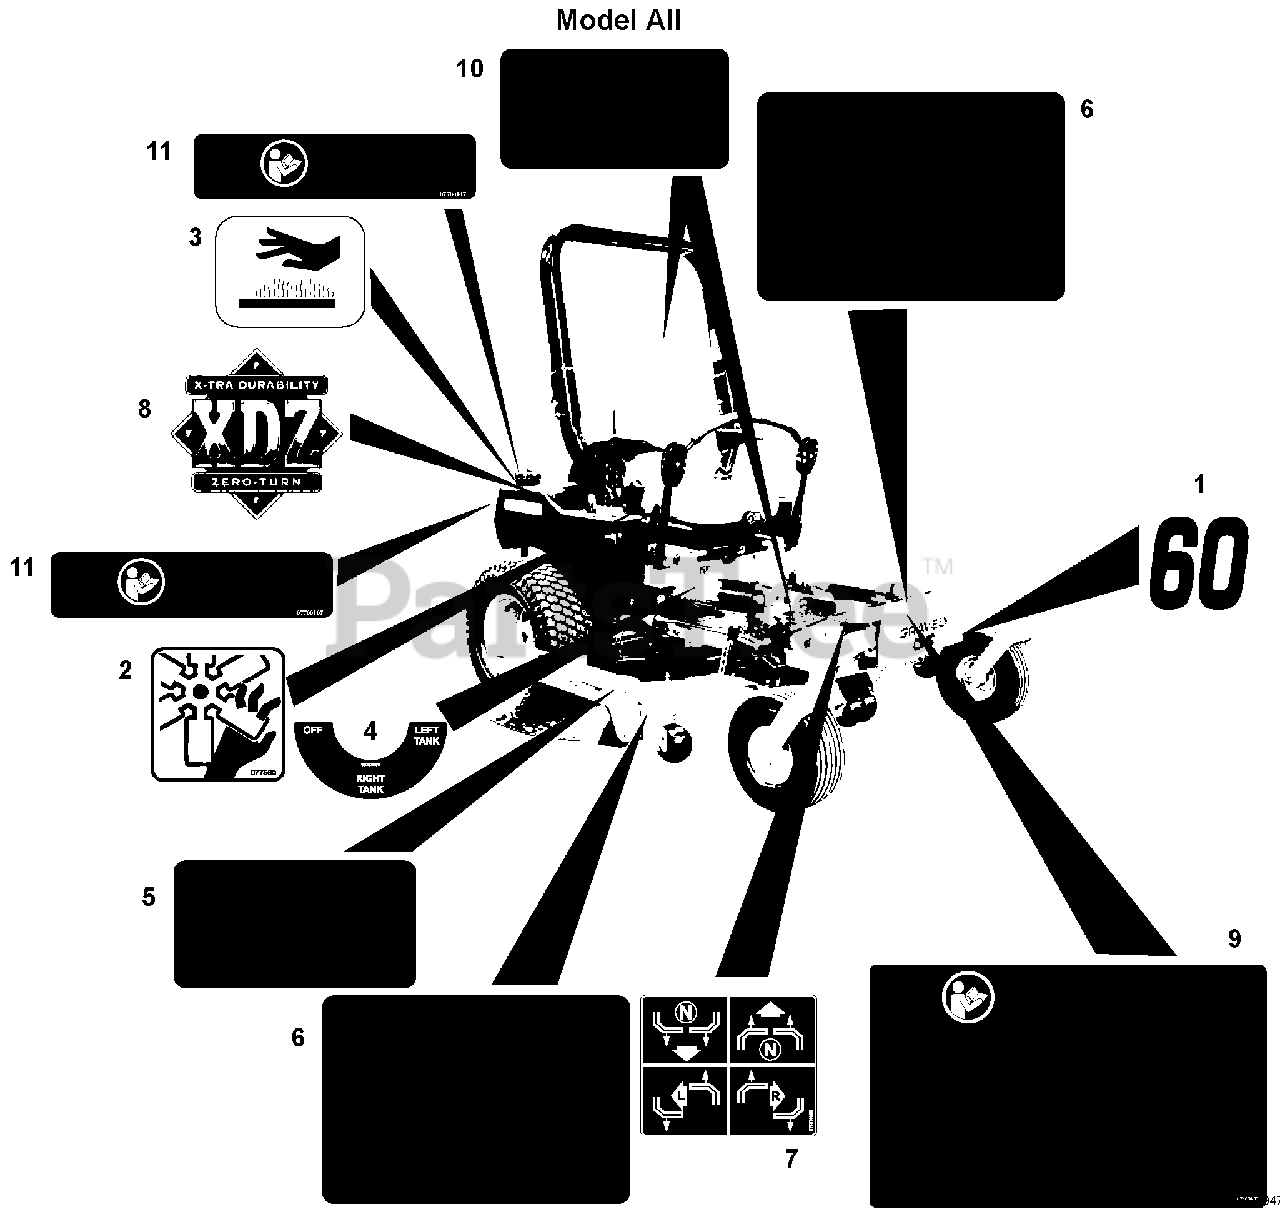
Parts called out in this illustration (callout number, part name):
1	Decal, 60
2	Decal, Danger Fan
3	Decal, Hot Surface
4	Set, Decal Fuel Valve
5	Decal, Safety Deck Guarding
6	Decal, Safety Mower Deck
7	Decal, Instructional
8	Decal, XDZ
9	Decal, Main Safety Commercial
10	Decal, Safety Guarding
11	Decal, Debris
